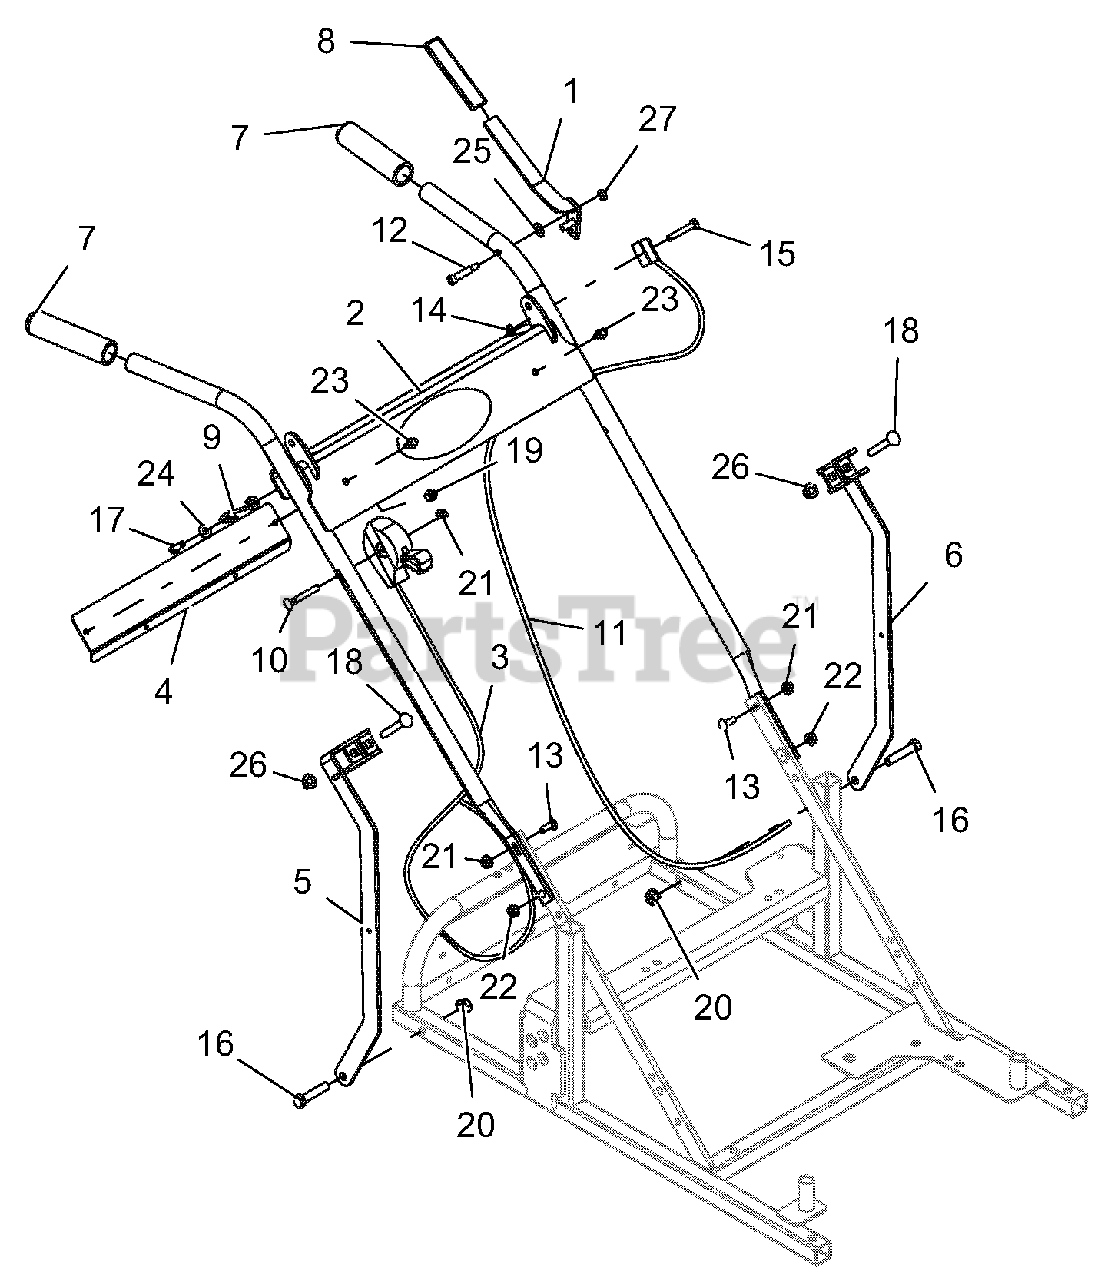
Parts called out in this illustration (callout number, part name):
1	LEVER, HIGH WHEEL OPC
2	HANDLEBAR, HWM SP W/ DECAL
3	CABLE, THROTTLE (NON-CHOKING)
4	BACKER, GRAVELY
5	WLDMT, RH HANDLEBAR SUPPORT
6	WLDMT, LH HANDLEBAR SUPPORT
7	GRIP, BLACK 7/8ID
8	GRIP MZR/MOMENT SP 7/8X3/4X4
9	GUIDE - PULLCORD
10	BLT-RDHDXLSQNK .25-20X2.0 G5YZ
11	CABLE,MRZ SYSTEM 2
12	SCR-SHLDR .25-20X1.00 -YWZC
13	@BLT-RDHDSQNK .25-20X.75 G5YZ
14	NUT-JAM-NYL .250-20 W/INSERTYZ
15	@BLT-HEX .25-20X1.50 GR5 YWZC
16	@BLT-HEX .38-16X1.75 GR5 YWZC
17	@BLT-HEX .25-20X.75 GR5 YWZC
18	@BLT-RDHDSQNK .31-18X2.25 G5YZ
19	@NUT-LK-NYL .250-20 YWZC
20	@NUT-LK-TOP-FLG .38-16 YWZC
21	@NUT-LK-TOP-FLG .25-20 YWZC
22	@NUT-LK-TOP-FLG .25-20 YWZC
23	SCR-TAP .25-20X.50 HWH TR YWZ
24	@WSHR-FL-STL.281X.62X.065 YWZC
25	@WSHR-FL-STL.344X.688X.065YWZC
26	@NUT-LK-NYL-FLG .31-18 YWZC
27	NUT-JAM-NYL .250-20 W/INSERTYZ
